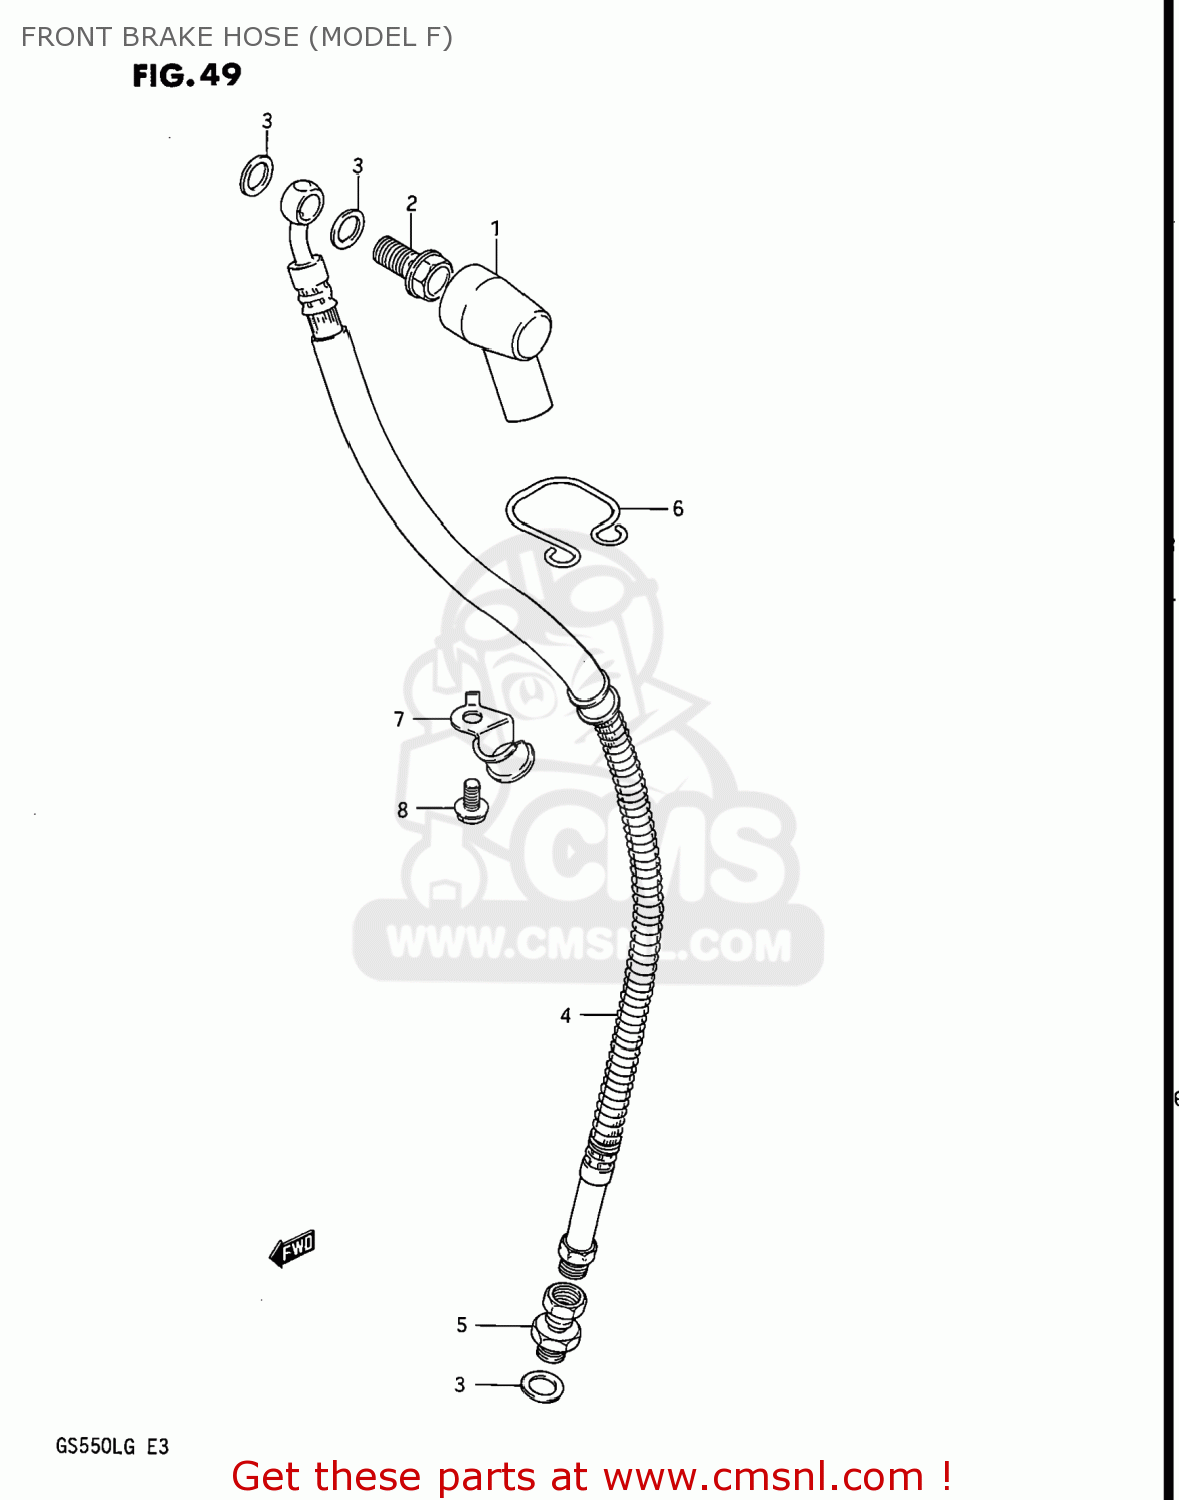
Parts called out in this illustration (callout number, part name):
1	BOOT,MASTER CYLINDER
2	BOLT UNION
3	WASHER(10X15X1.5)
4	HOSE,FRONT BRAKE
5	ADAPTER,BRAKE HOSE
6	GUIDE,CABLE/HARNESS
7	GUIDE,BRAKE HOSE NO.3
8	BOLT
